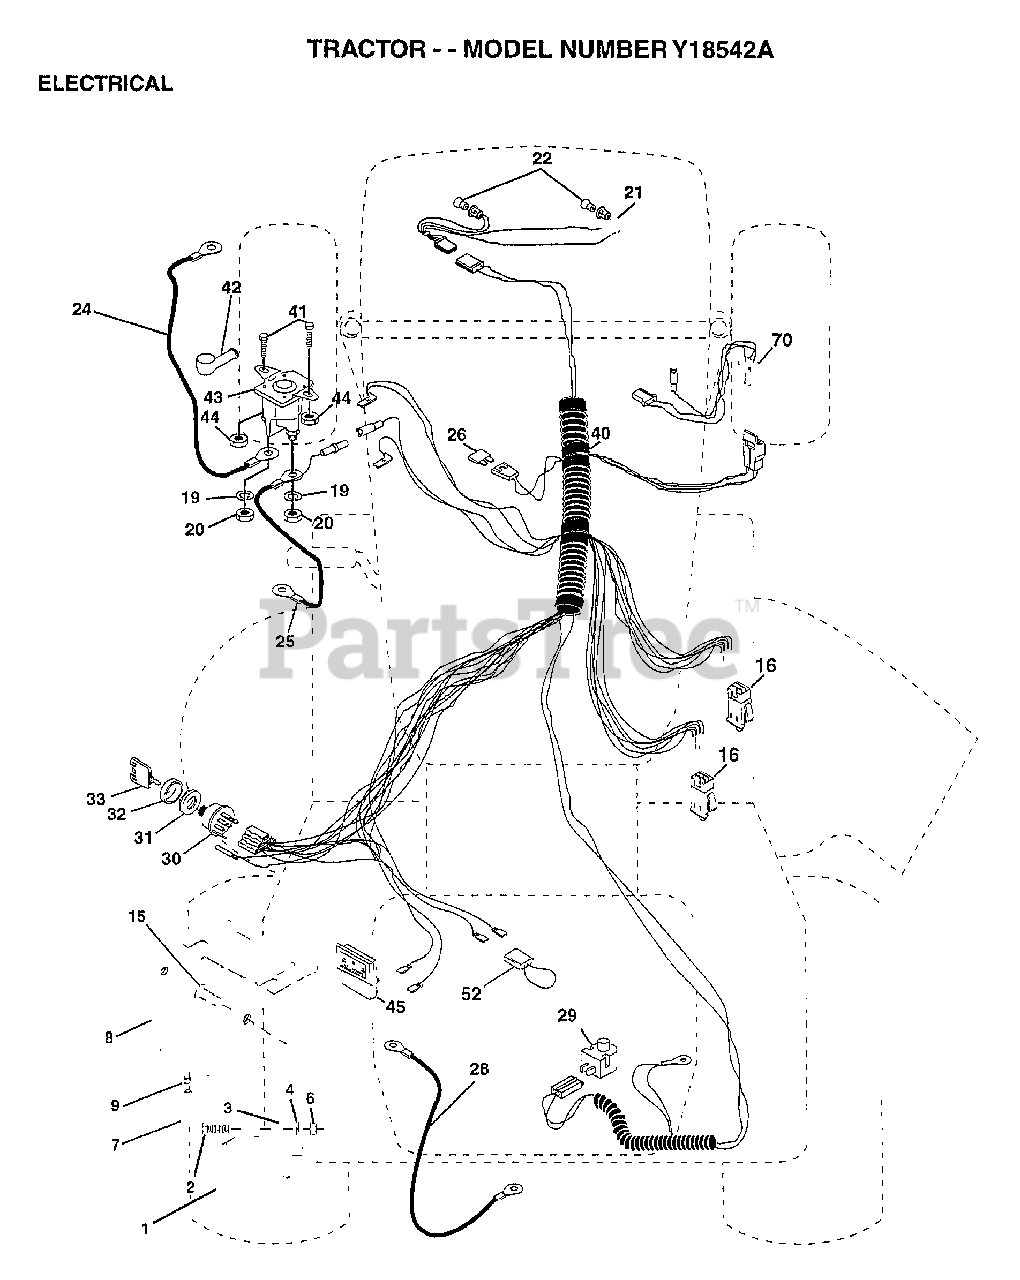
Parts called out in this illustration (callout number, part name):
2	BOLT LT
3	WASHER
4	LOCKWASHER
7	TUBE T
8	"CASE,BATTERY.MECH"
9	HOSE CLAMP T
15	FASTNER.SNAP-IN
16	SWITCH INTERLOCK
20	NUT
21	"HARNESS,LIGHT SOC"
22	HEADLAMP BULB
24	"CABLE T, BATTERY"
25	CABLE.BTRY.6GA.RD
26	FUSE HYT
28	CABLE T
29	SWITCH SEAT
30	SWITCH IGN 4POS
31	NUT IGNITION
32	COVER KEY SWITCH
33	KEY
40	HARNESS-IGNITION
41	BOLT HXHD FIN
44	NUT HXKEP 1/4X20
52	PROTECTION LOOP
70	HARNESS ENG DUAL
